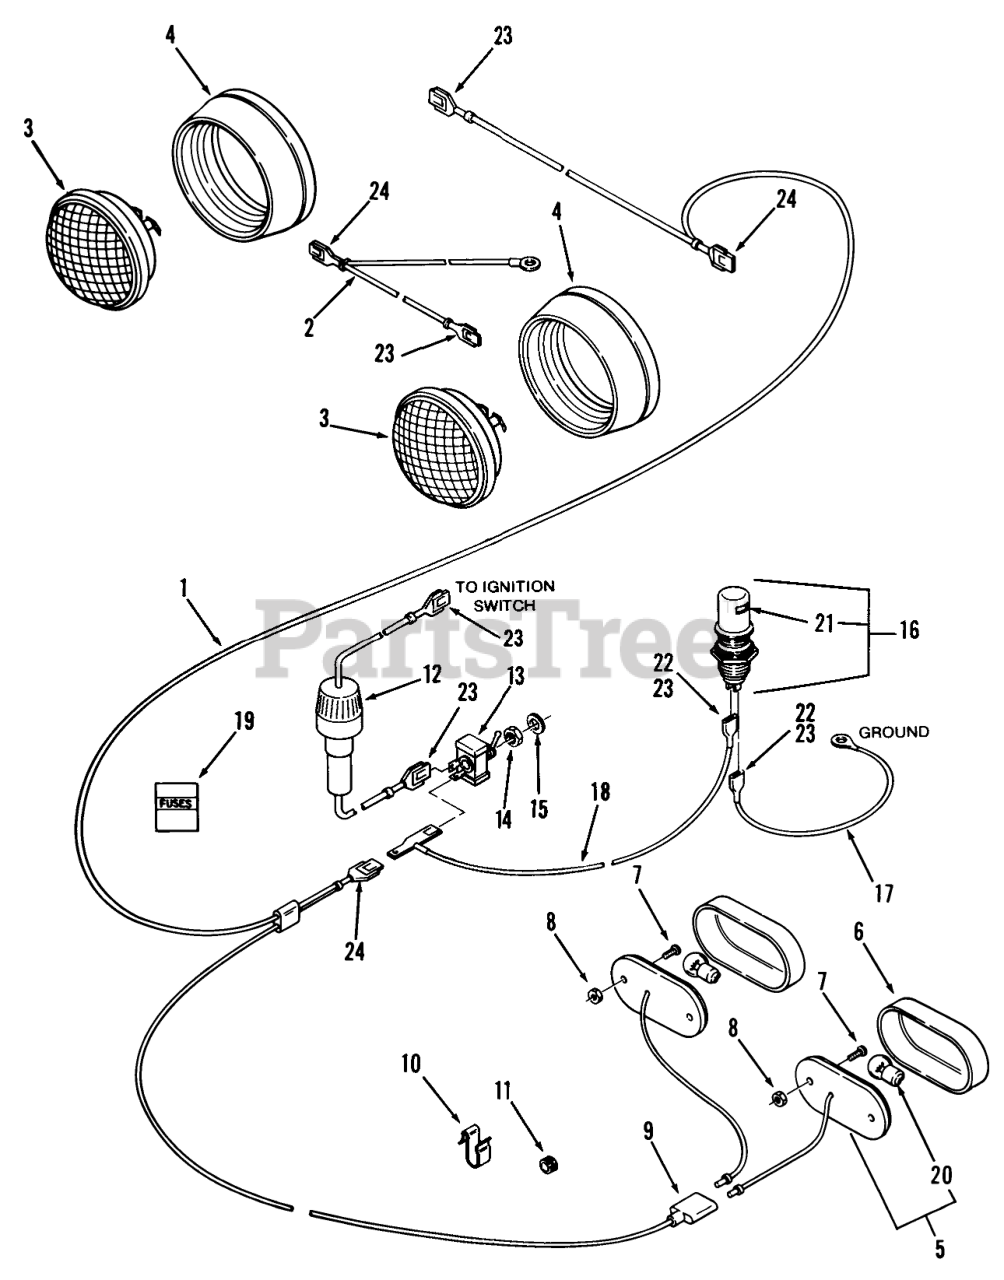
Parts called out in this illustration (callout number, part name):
3	HEADLAMP
8	HEX NUT 10-32 E.S. + + USE 3296-21 + +
13	SWITCH-LIGHTS
15	NUT-HEX
20	Bulb
21	Bulb (#1815)
22	CONNECTOR BODY ELECT
24	TERMINAL-TAB RCPT
